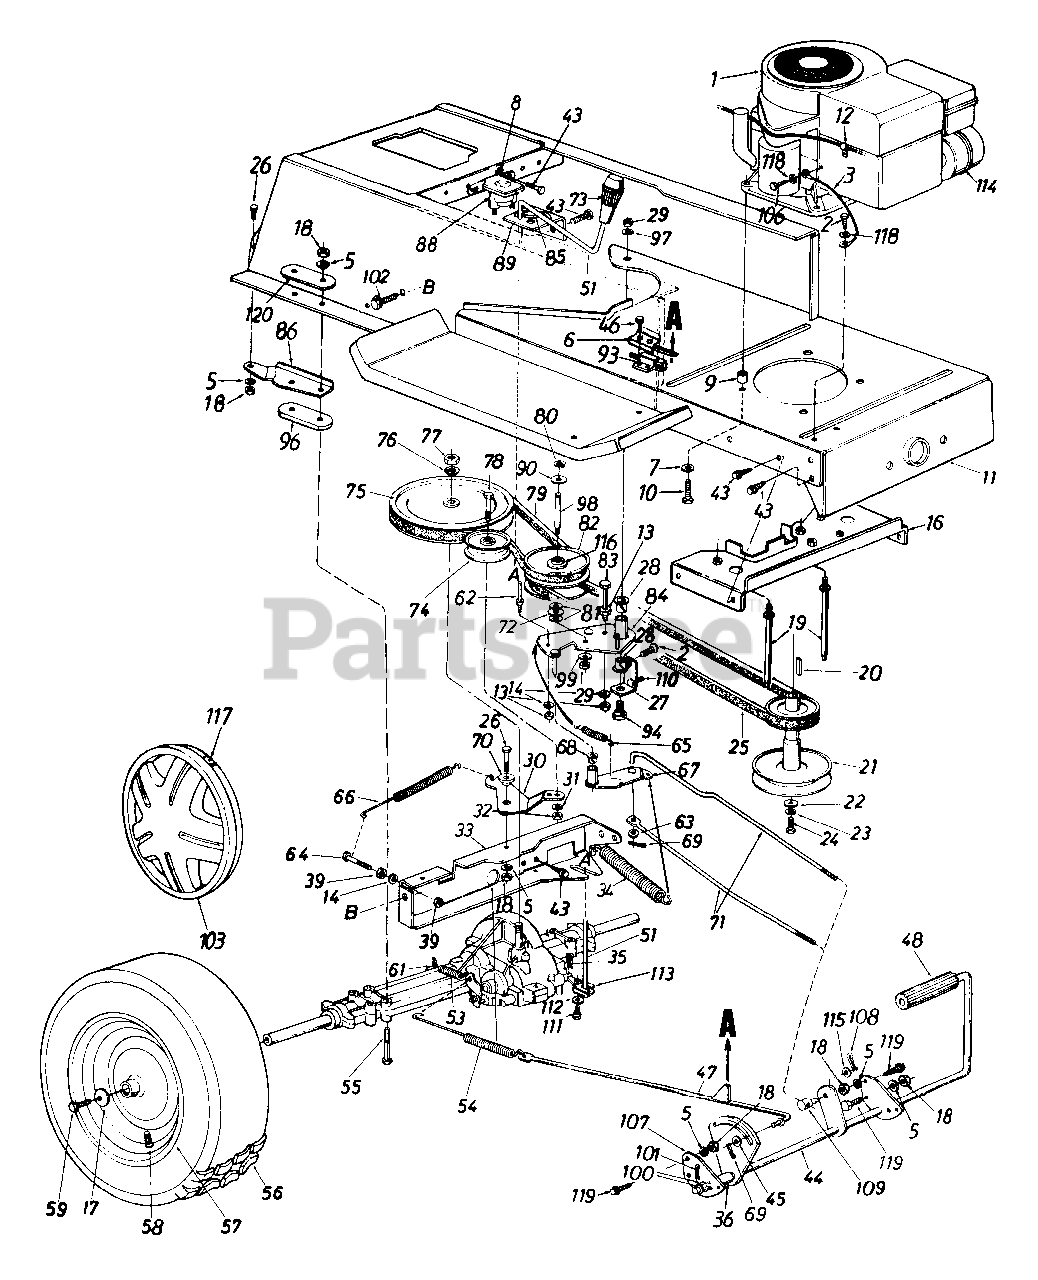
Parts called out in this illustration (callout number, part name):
1	Engine
2	Hex Wash. AB-Tap Scr. 5/16" x .75"
3	Electric Ground Wire
5	L-Wash. 5/16" I.D.
6	Switch Plate
7	Fl-Wash. .406" I.D. x 1.25"
8	Ext. L-Wash. 1/4" I.D.
10	Hex L-Wash. Tap Scr. 3/8-16 x 1.5" Lg.
11	Lower Frame Ass'y.
13	Hex Nut 1/4-20 Thd.
14	L-Wash. 1/4" I.D.
16	Belt Guard Brkt. Ass'y.
17	Bell-Wash. .345" I.D. x .88"
18	Hex Nut 5/16-18 Thd.
19	Belt Guard Pin 3.6" Lg.
20	Sq. Key 1/4" x 1/4" x 2.00"
21	Engine Pulley
22	Fl-Wash. 7/16" I.D. x 1.25"
23	L-Wash. 7/16" I.D.
24	Hex Bolt 7/16-20 x 1.50" Lg.
25	Variable-Speed Belt
26	Hex Bolt 5/16-18 x .75" Lg.
27	Bearing Shaft Bracket Ass'y.
28	Flanged Nyliner Brg. .63" I.D. x .6" Lg.
29	Hex Nut 3/8-24 Thd.
31	L-Wash. 3/8" I.D.
32	Hex Nut 3/8-24 Thd.
35	Internal Cotter Pin
36	Spacer .63" I.D.
39	Hex Nut 1/4-28 Thd.
43	Hex Wash. Hd. S-Tap Scr. 1/4-20 x .50" Lg.
46	Truss Mach. B-Tap Scr. #10 x .5" Lg.
47	Brake Rod Ass'y.
48	Foot Pad
51	Shift Lever Ass'y.
53	Ext. Spring .38" O.D. x 2.5"
54	Ext. Spring 7.08"
55	Hex Bolt 5/16-18 x 3" Lg.
57	Wheel Rim Only
58	Air Valve
59	Hex Bolt 5/16-24 x .75" Lg.
61	Brake Return Spring Anchor
62	Belt Guard Pin 1/4-20 Thd.
63	Fl-Wash. .34" I.D. x .68" O.D.
64	Hex Bolt 1/4-28 x 1.25" Lg.
65	Ext. Spring
66	Ext. Spring .62" O.D. x 6.12"
68	Flanged Bearing
69	Cotter Pin 3/32" Dia.
70	Shoulder Spacer .27" Lg.
71	Speed Control Link
72	Truss Bearing .56 Dia. x 1.25"
73	Shift Knob
74	Fl-Idler Pulley 3.25"
76	Bell-Wash. .56" I.D. x 1.125"
77	Hex Jam Nut 9/16-18 Thd.
78	Hex Bolt 3/8-24 x 1.75" Lg.
79	Variable Speed Belt
80	Snap Ring .56" Dia.
82	Variable Speed Pulley Ass'y. 5" O.D.
83	Hex Bolt 1/4-20 x 3.5" Lg.
90	Teflon Washer .565" I.D.
93	Safety Switch (Clutch)
94	Shld. Bolt 3/8-24 x 3.12" Lg.
97	Bell-Wash. .38" I.D. x .88"
98	Shaft .56" Dia. x 3.875" Lg.
99	Bell-Wash. .39" I.D. x 1.12"
100	Fl-Wash. .64" I.D. x .94"
101	Cotter Pin 1/8" Dia. x 1.25"
102	Hex Wash. Hd. Scr. 5/16-18 x .62" Lg.
103	Hub Cap
106	Pan Hd. Mach. Scr. 5/16-18 x .75" Lg.
109	Ferrule
110	Hex Bolt 5/16-18 x 1.0" Lg. - (Gr. 5)
111	Hex Bolt 1/4-28 x .50" Lg.
112	Bell-Wash. .265" I.D. x .75"
113	Shift Lever Link Ass'y.
114	Muffler
115	Fl-Wash. .385" I.D. x .62"
116	Needle Brgs.
117	Spring Clip
118	External L-Wash. 5/16" I.D.
119	Hex Wash.TT-Tap Scr. 5/16-18 x .75"
